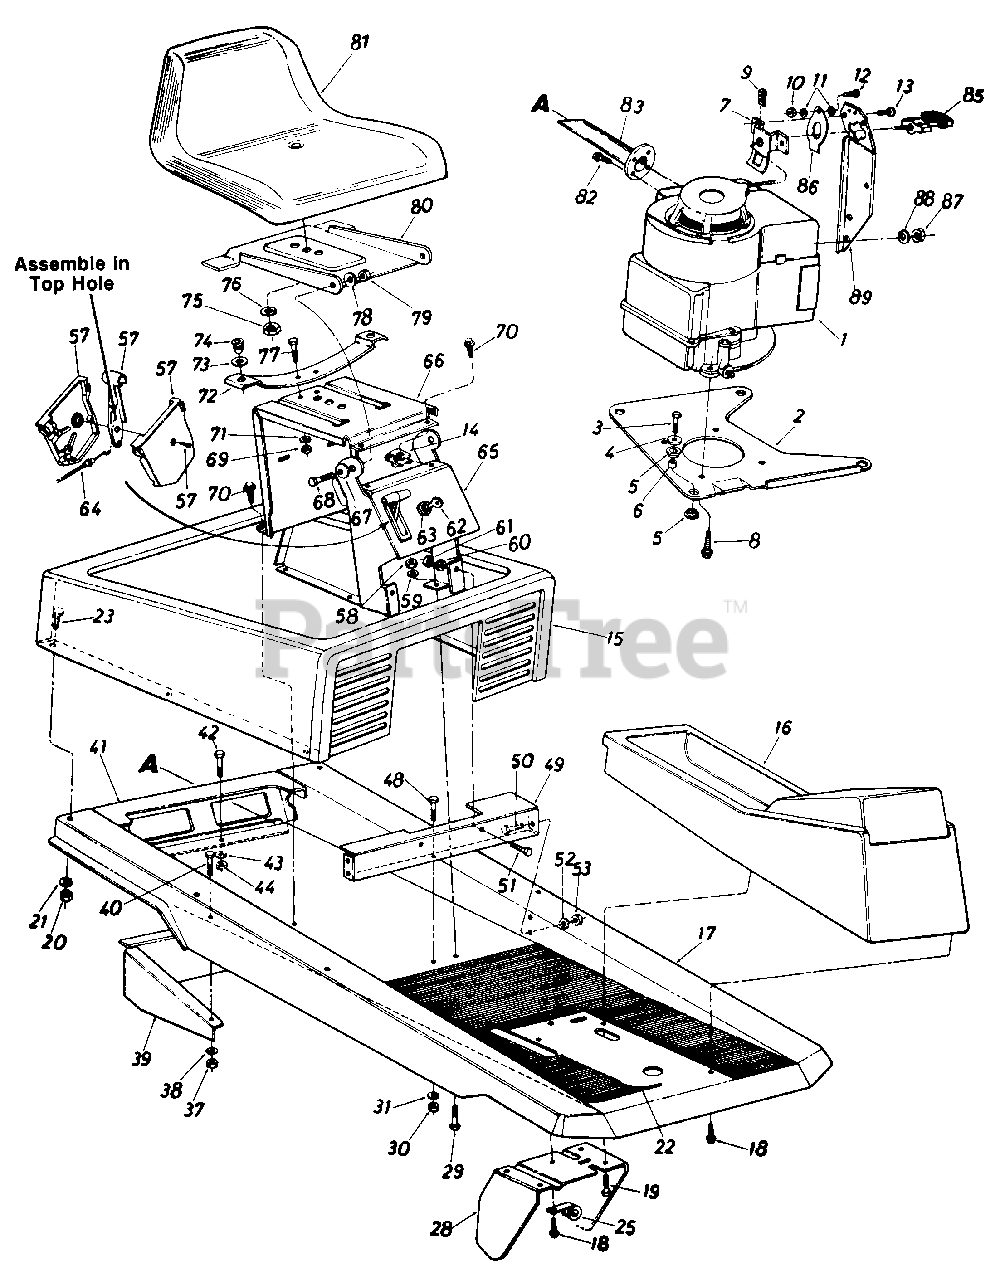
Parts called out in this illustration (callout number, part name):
2	PLATE-ENGINE MTG
3	SCREW-HEX 5/16-24 X 1.25
4	WASHER-FL-.312 X 1.125 X .125
5	MOUNT-ENGINE
6	SPACER
7	BRACKET ASSY-SWITCH
8	SCREW-HEX SLF TAP 3/8 X 1 3/8
9	NUT-SPEED-10-24
11	WASHER-FIBER
12	SCREW-TRUSS MACH #10-24 X .62
13	SCREW-TRUSS MACH
15	COVER ASSY
16	CONSOLE-FR
17	FRAME
18	SCREW-PLASTIC-5/16X1.0
19	SCREW-HEX 5/16-18 X .75
20	NUT-HEX 1/4-20
21	LOCK WASHER 1/4 DIA
22	MAT-FLOOR
23	SCREW-HEX 1/4-20 X .50
28	PEDAL ASSY-BRAKE
29	SCREW-HEX 5/16-18 X .62
30	NUT-HEX 5/16-18
31	WASHER-LOCK-5/16
37	NUT-HEX 5/16-18
38	WASHER-LOCK-5/16
43	WASHER-LOCK-5/16
44	NUT-HEX 5/16-18
48	SCREW-HEX 5/16-18 X .75
49	BRACKET-SEAT SUP
50	SCREW-HEX 5/16-18 X .52
51	SCREW-HEX 5/16-18 X .52
52	WASHER-LOCK-5/16
53	NUT-HEX 5/16-18
57	CONTROL-THROTTLE
58	NUT-HEX 5/16-18
59	WASHER-LOCK-5/16
60	WASHER-LOCK-5/16
61	NUT-HEX 5/16-18
62	KEY-IGN (SET OF TWO)
63	SWITCH-KEY TYPE
64	WIRE-CONTROL
65	BRACKET-SEAT
66	KIT-SEAT BRKT ASSY
67	WASHER-BELL .337 X .867 X .057
68	SCREW-HEX 5/16-18 X .75
69	NUT-HEX 5/16-18
70	SCREW-HEX WASH SF TAPP
71	WASHER-FL-.40 X .88 X .060
72	SPRING-SEAT
73	WASHER-FL-.531 X .930 OD X .050
75	NUT-HEX 1/2-13
76	WASHER-LOCK-1/2
77	SCREW-HEX 5/16-18 X .62
78	WASHER-BELL .337 X .867 X .057
79	NUT-HEX CENTER L-5/16-18
80	BRACKET-SEAT PIVOT
82	SCREW-SL HEX SLF EX
83	PIPE ASSY-EXHAUST
85	HANDLE-PLASTIC
86	SPRING-SWITCH
87	NUT-HEX 5/16-18
88	WASHER-LOCK-5/16
89	BRACKET-ROPE HDLE
